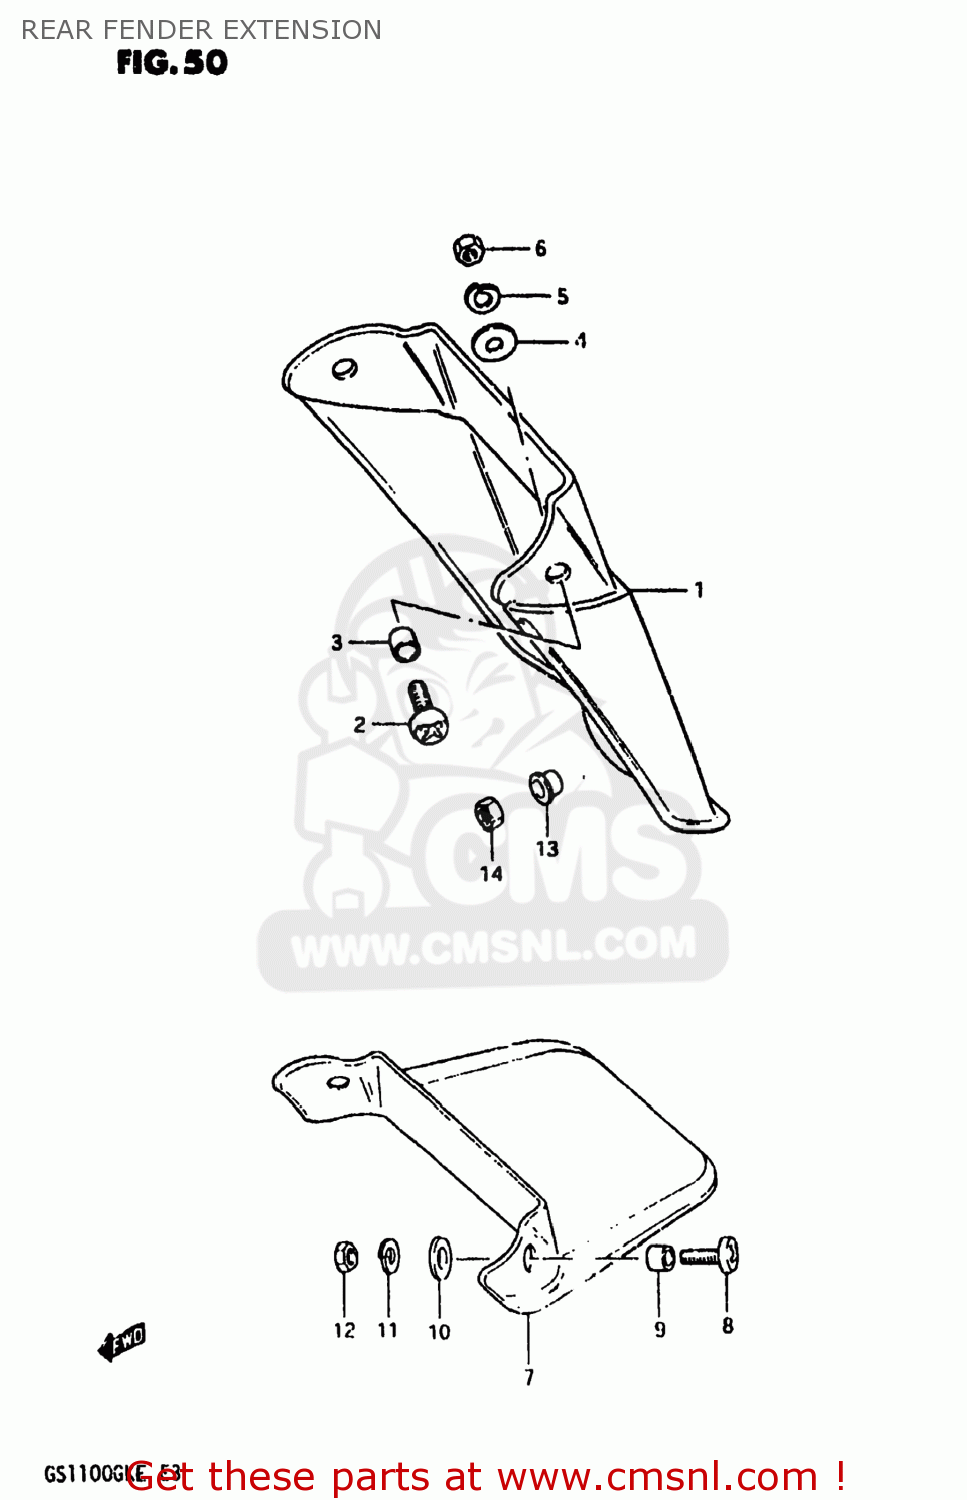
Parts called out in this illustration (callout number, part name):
1	EXTENSION,REAR FENDER
2	SCREW (6X15)
3	SPACER(6.2X8.3X5.7)
4	WASHER(6.5X18X1)
5	LOCK WASHER
6	NUT
7	EXTENSION,REAR FENDER
8	SCREW (6X15)
9	SPACER(6.2X8.3X5.7)
10	WASHER(6.5X18X1)
11	LOCK WASHER
12	NUT
13	SPACER
14	NUT
